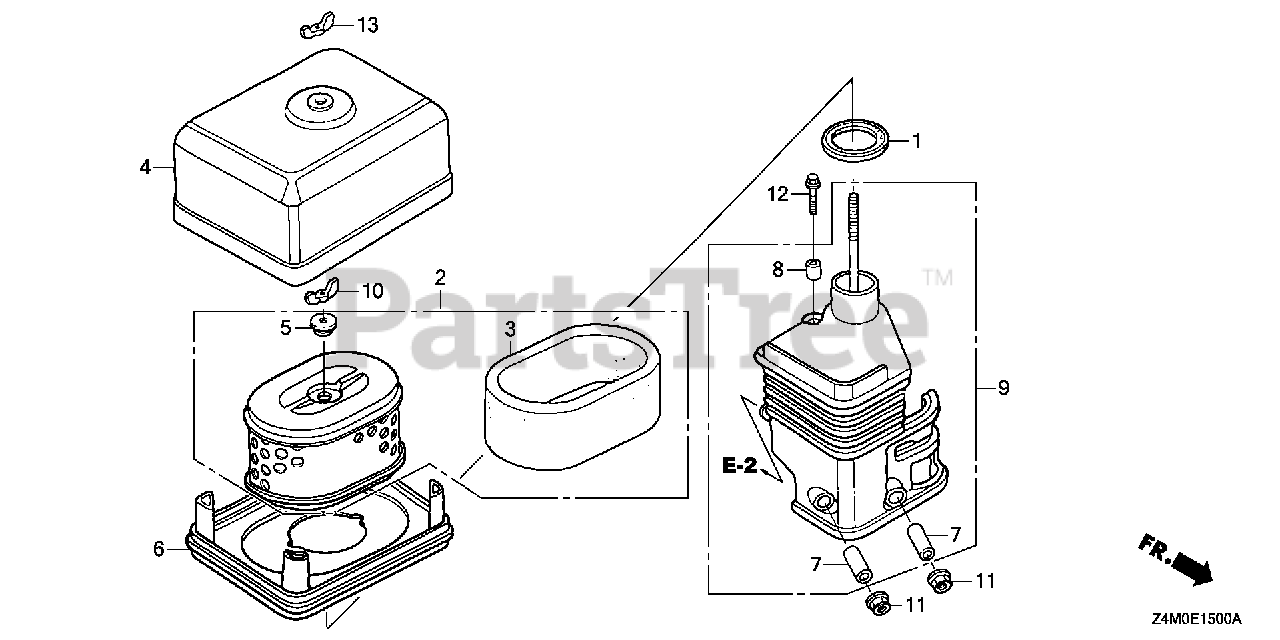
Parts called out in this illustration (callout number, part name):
1	GASKET, ELBOW
2	ELEMENT, AIR CLEANER (DUAL) Use up to Engine SN 2115700.
2	ELEMENT, AIR CLEANER (DUAL)
3	FILTER (OUTER)
4	COVER, AIR CLEANER (DUAL)
5	GROMMET, AIR CLEANER
6	NOSE, MUFFLER
7	COLLAR, AIR CLEANER Use from Engine SN 1786085.
8	COLLAR B, AIR CLEANER
9	ELBOW, AIR CLEANER
10	WINGNUT, TOOL BOX SETTING
11	NUT, FLANGE (6MM)
12	BOLT, FLANGE (6X20)
13	WINGNUT, TOOL BOX SETTING
